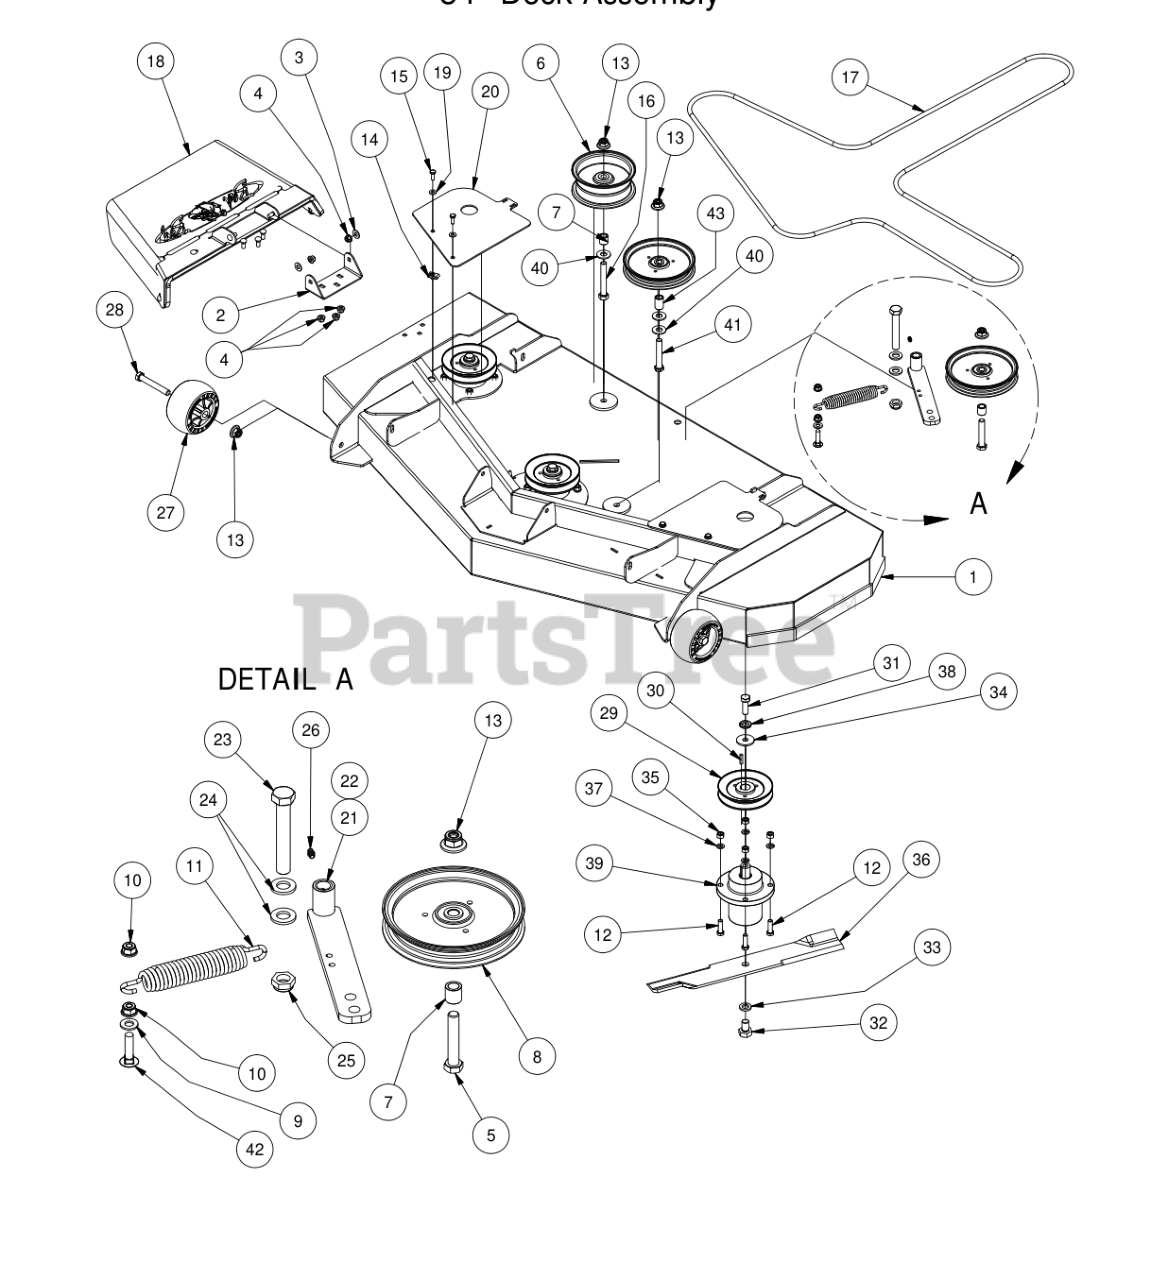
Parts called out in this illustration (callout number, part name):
1	54 MZ Deck
2	Chute Hanger 48 MZ
3	.360 ID Plastic Washer
4	5/16" Nylon Flange Nut
5	1/2" x 2 3/4" Hex Bolt
6	5 3/4" Deck Idler Pulley
7	3/4" OD x 1/2" ID x 3\4" Length
8	5-3/4 Idler Pulley
9	3/8" Flat Washer
10	3/8" Nylock Flange Nut
11	2009 Deck/Pump Idler Spring
12	3/8" x 1 1/4" Hex Bolt
13	1/2"-13 Nylon Flange Nut-Orange
14	1/4"-20 Cage Nut
15	1/4" x 3/4" Hex Bolt
16	1/2"-13 x 3 1/2" GR 5 Hex Bolt
17	B 138 Deck Belt
18	MZ Discharge Assembly
19	1/4" Flat Washer
20	2014 54" MZ Mag Pulley Cover
21	Deck Idler Arm
22	Deck Idler Assembly
23	5/8" x 4" Hex Bolt
24	635 ID Plastic Wash
25	5/8"-11 Nylon Insert Jam Half Nut
26	1/4" Press in Grease Fitting
27	Deck Wheel
28	Deck Wheel Bolt
29	MZ Deck Pulley
30	3/16 x 1 Square Key
31	1/2"-20 x 1 1/2 - Grade 5 Fine Thread Bolt
32	5/8" x 1 1/2" Grade 8 Hex Bolt (Fine)
33	5/8" Lock Washer
34	1/2 Belleville Washer
35	3/8" Hex Nut
36	54" MZ Fusion Blade
37	3/8" Lock Washer
38	1/2" Lock Washer Zinc
39	Spindle Assembly
40	1/2" Washer (Grade 8)
41	1/2" x 3" Hex Bolt
42	3/8 x 1 1/2 Carriage Bolt
43	.502 x .750 x 1.25 Length Spacer
